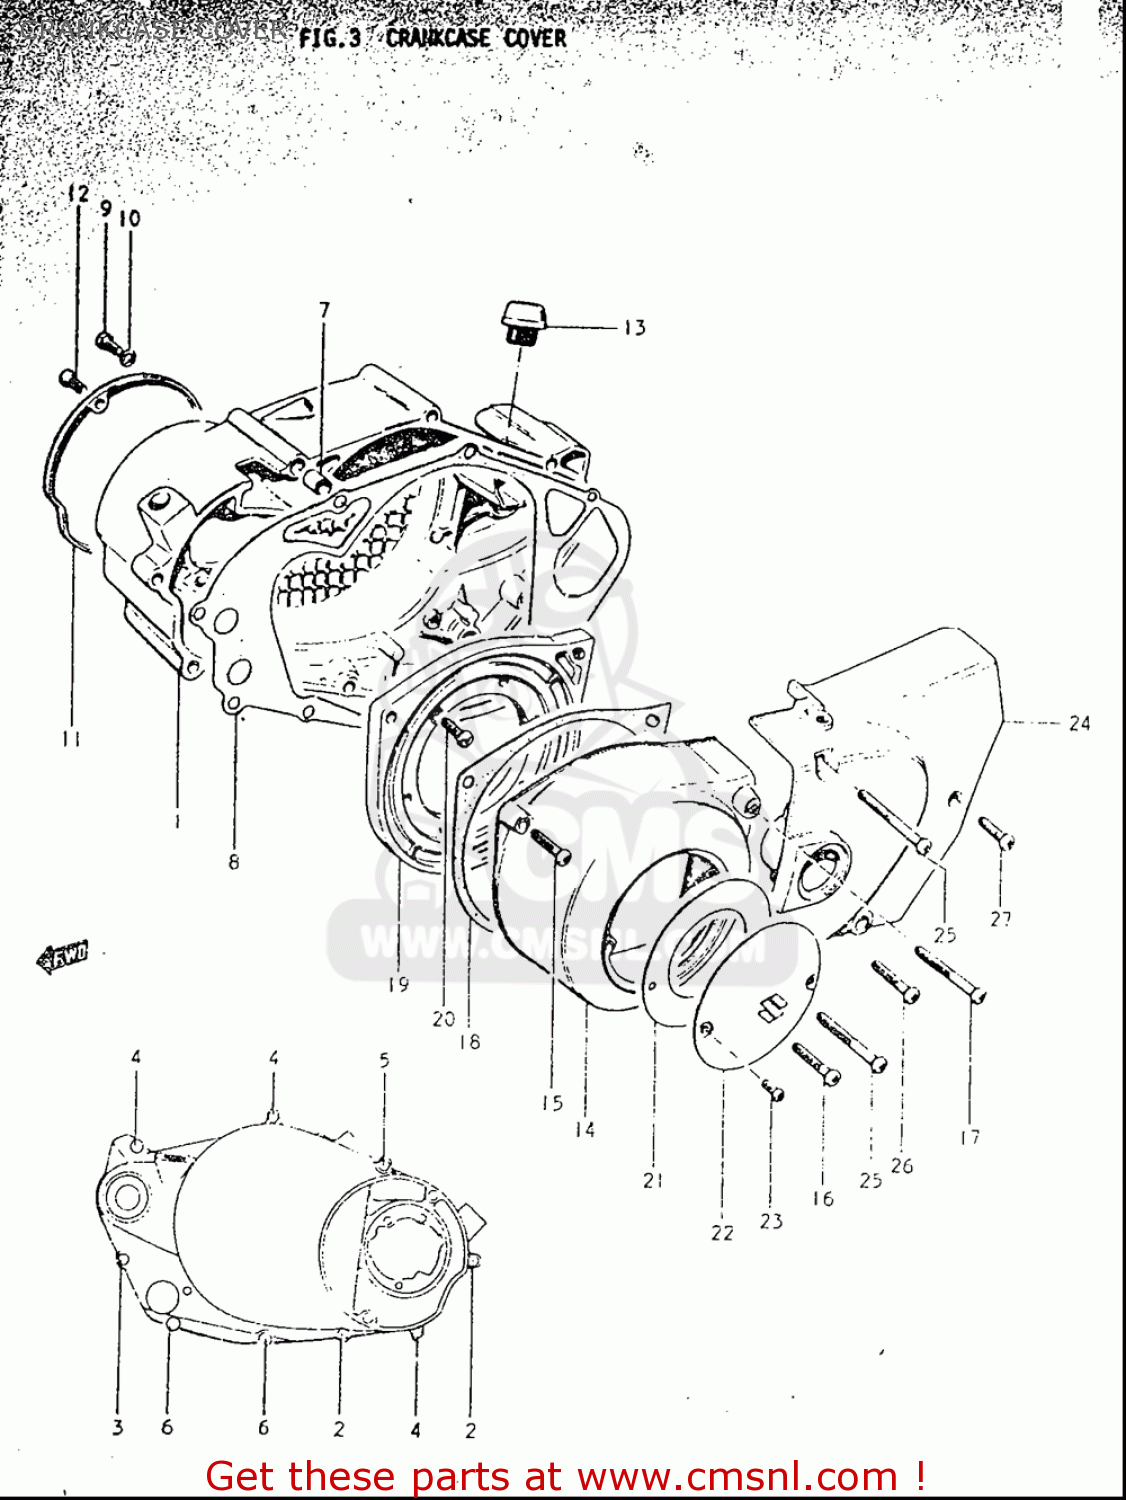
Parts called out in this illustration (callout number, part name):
2	SCREW
3	SCREW
4	SCREW
5	SCREW
6	SCREW
7	PIN
8	GASKET (MCA)
10	GASKET(6.2X11X1) (NAS)
13	PLUG SET
17	SCREW
21	GASKET,OIL PAN (MCA)
25	SCREW
26	SCREW
27	SCREW
